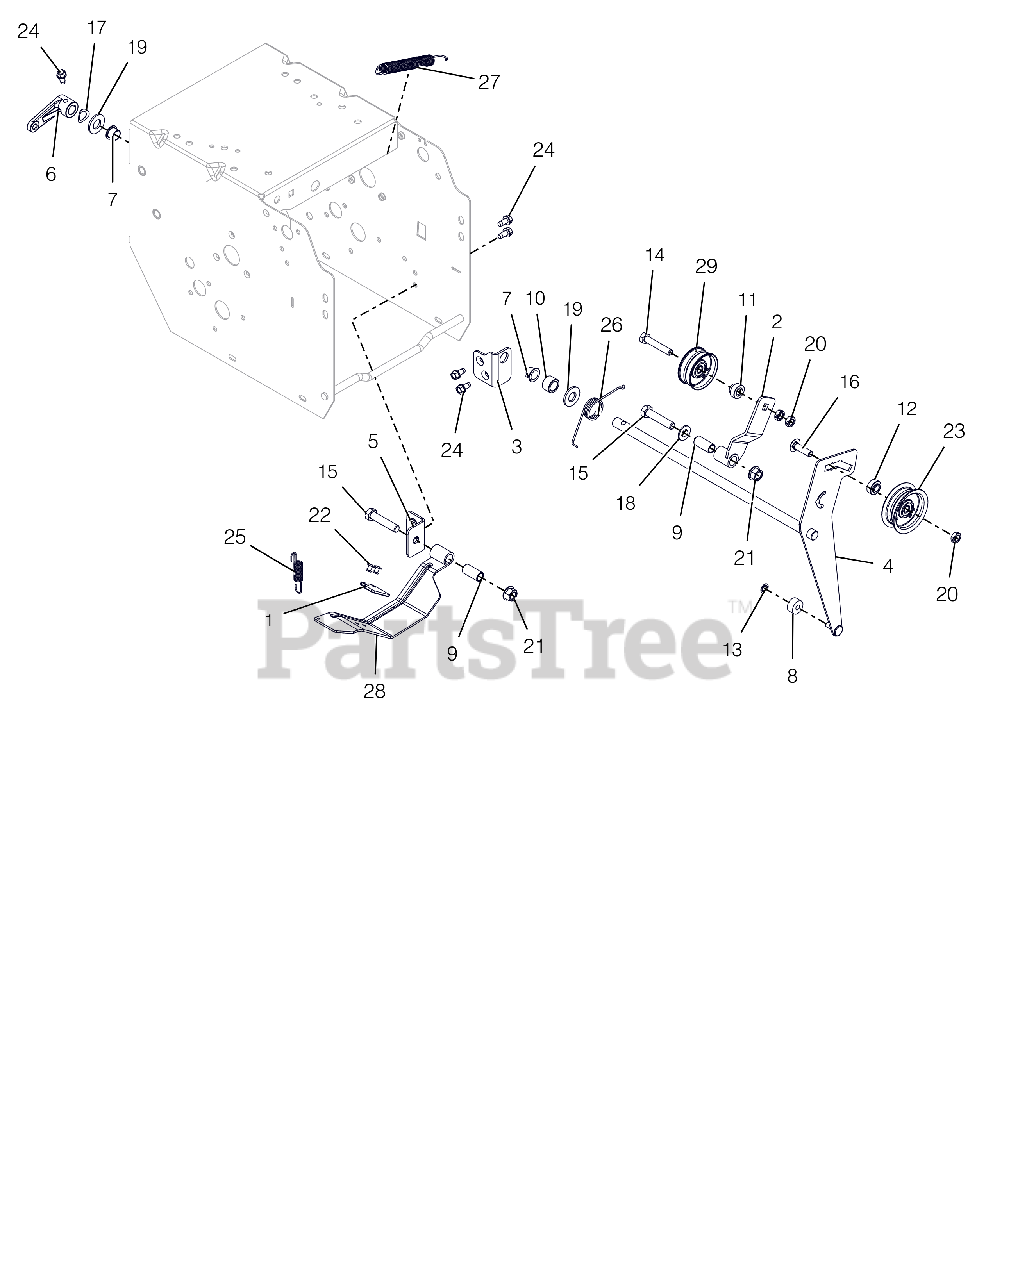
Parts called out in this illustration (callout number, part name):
1	PAD, BRAKE
2	ARM, TRACTION IDLER
3	BRACKET, MOUNT - IDLER ARM
4	WELDMENT, ATTACHMENT IDLER ARM
5	BRACKET, MOUNT - BRAKE
6	ARM, CLUTCH - ATTACHMENT
7	BUSHING, POLYLINER-.50 SPLIT
8	BSHG,SLV .265 X .625 X .375
9	BSHG-SLV .385X.500X1.045
10	BSHG-SLV .510X.751X.475
11	SPCR, BRG .315X.500X.481X.281
12	SPCR, BRG .315X.500X.358X.281
13	RG-RTNG-EXT .250X.010
14	@BLT-HEX .31-18X1.75 GR5 YWZC
15	@BLT-HEX .38-16X1.75 GR5 YWZC
16	BLT-RDHDSQSHNK.31-18X1.13 G5YZ
17	WSHR-WAVE .50X.75X.015 .13FRHT
18	@WSHR-FL-STL.406X.812X.065 YWZ
19	@WSHR-FL-STL.531X1.06X.095YWZC
20	@NUT-LK-CTR-JAM .31-18 YWZC
21	@NUT-LK-TOP-FLG .38-16 YWZC
22	RVT-POP .187 YZ
23	IDLER, FLAT - 2.00"
24	SCR-TAP .25-20X.50 HWH TR YWZ
25	SPRING-EXT .437 X .438 X 2.64
26	SG-TORS .075 X .955
27	SPRING, EXTENSION
28	BRAKE ARM W/PAD
29	IDLER, FLAT - 1.875"
